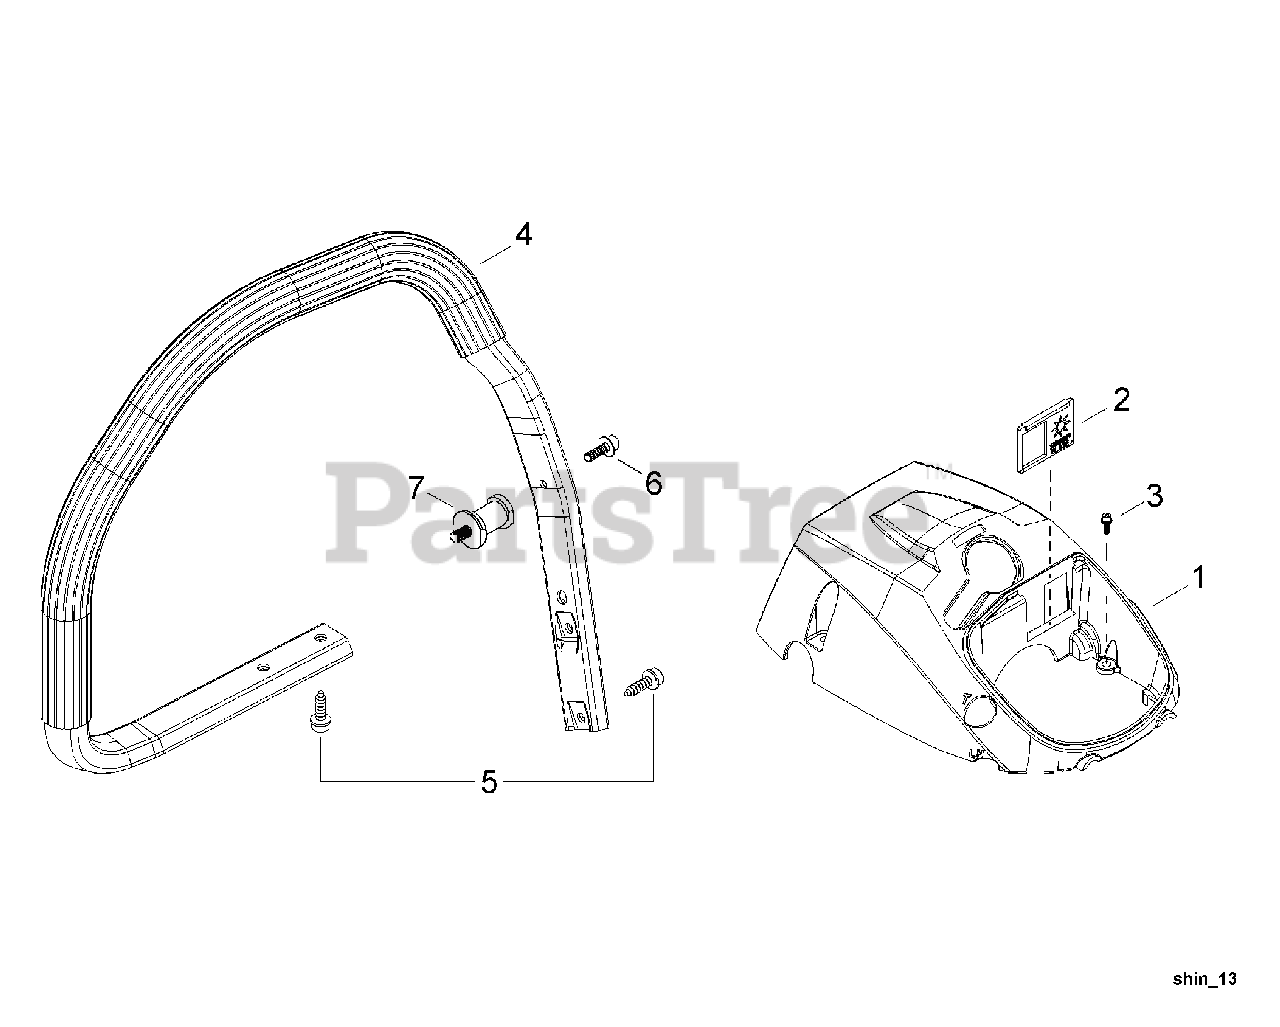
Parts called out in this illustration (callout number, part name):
1	COVER, ENGINE
2	SHUTTER
3	SCREW - 4X16
4	HANDLE - FRONT
5	BOLT - 5X16 -- TAPPING
6	SCREW - 4X14
7	CUSHION
